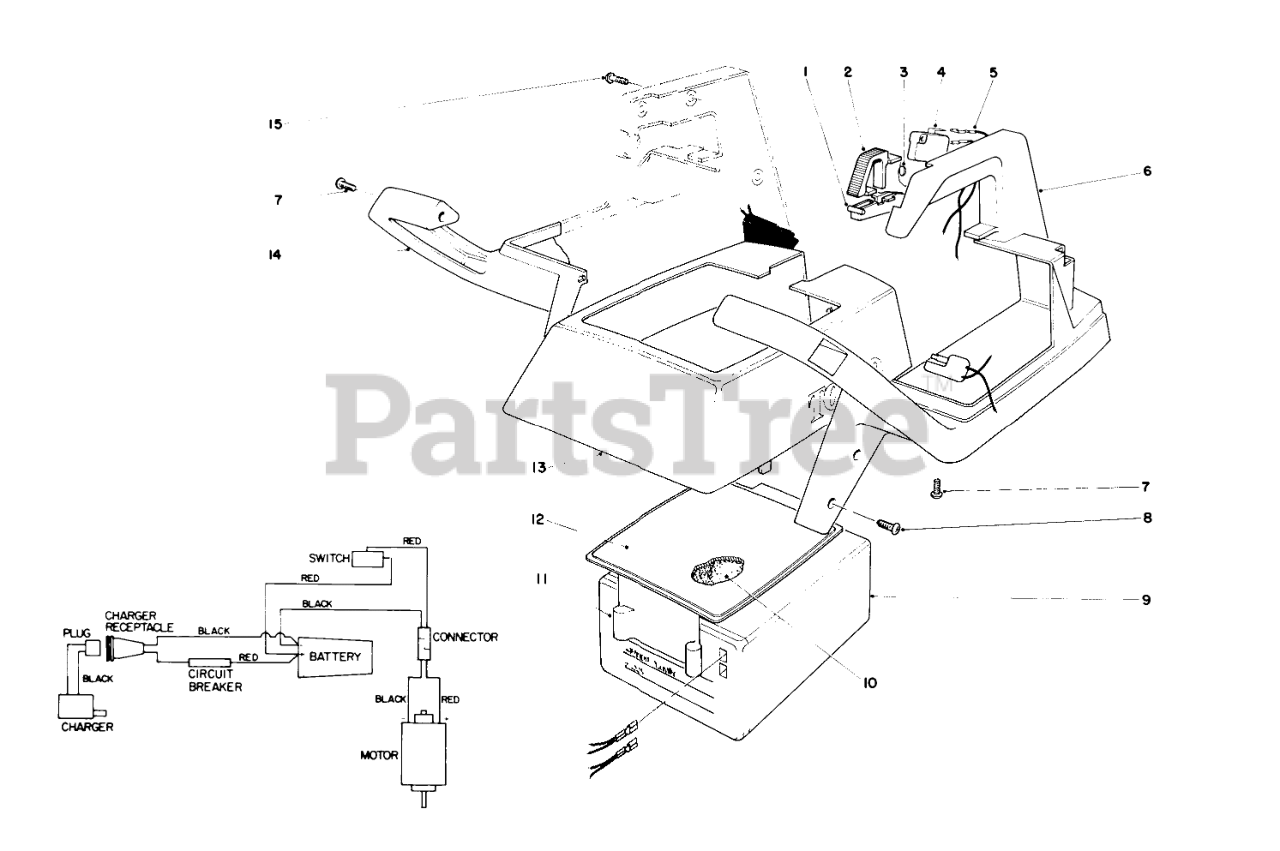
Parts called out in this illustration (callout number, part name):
1	TRIGGER
2	TRIGGER LOCK
3	SPRING
4	Switch
5	Wiring Harness
6	LH BATTERY CASE/HNDL
7	Screw
8	10-16 X .31 SCREW
9	BATTERY
10	FOAM PAD
11	CONTROL PANEL, CL-710
12	DECAL CL 710 PANEL
13	Cover
14	RH BATTERY CASE/HNDL
15	SCREW-PPH
